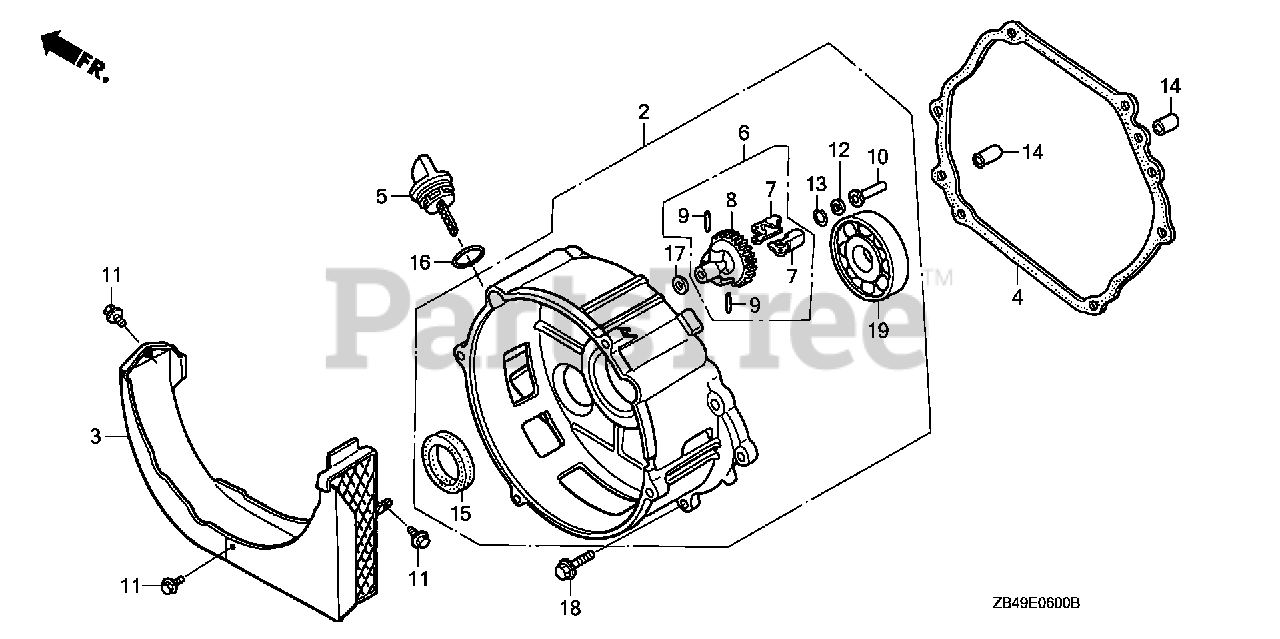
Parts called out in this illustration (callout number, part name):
2	COVER ASSY., CRANKCASE
3	COVER, DUCT
4	GASKET, CASE COVER
5	CAP, OIL FILLER
6	GOVERNOR ASSY.
7	WEIGHT, GOVERNOR
8	HOLDER, GOVERNOR WEIGHT
9	PIN, GOVERNOR WEIGHT
10	SLIDER, GOVERNOR
11	BOLT, FLANGE (5X10)
13	CLIP, GOVERNOR HOLDER
14	PIN, DOWEL (8X12)
15	OIL SEAL (30X46X8)
16	O-RING (26X2.7)
17	WASHER, PLAIN (6MM)
18	BOLT, FLANGE (8X35)
19	BEARING, RADIAL BALL (6206)
